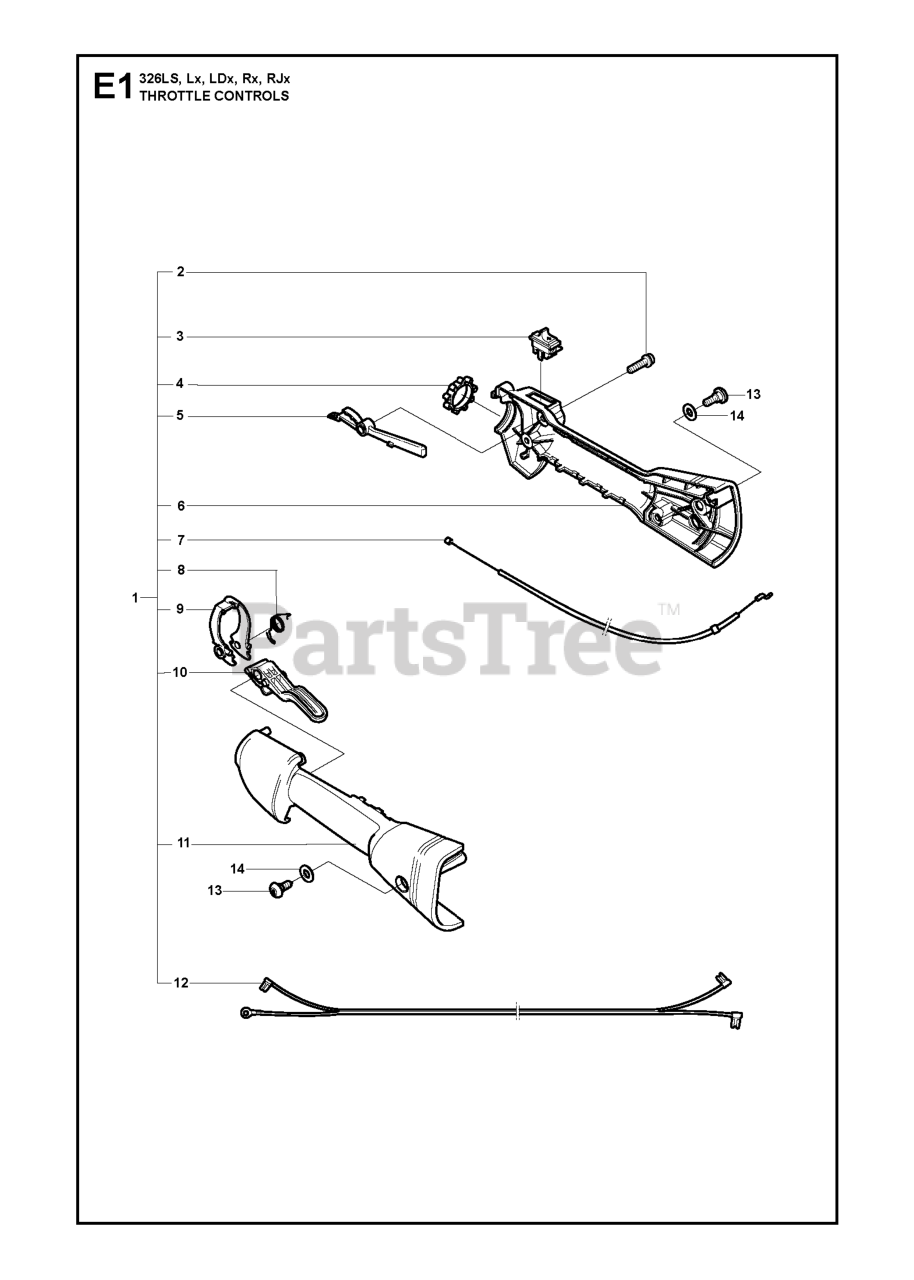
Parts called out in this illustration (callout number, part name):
3	STOP BUTTON
4	VIBRATION DAMPER
5	THROTTLE LOCK
6	HANDLE
6	HSG THROTTLE RH
7	THROTTLE WIRE ASSY
10	THROTTLE TRIGGER
11	HANDLE HALF HSG LH
11	HANDLE
12	SHORT-CIRCUIT CABLE
13	SCREW MT5X11
14	O-RING 8X1.6
